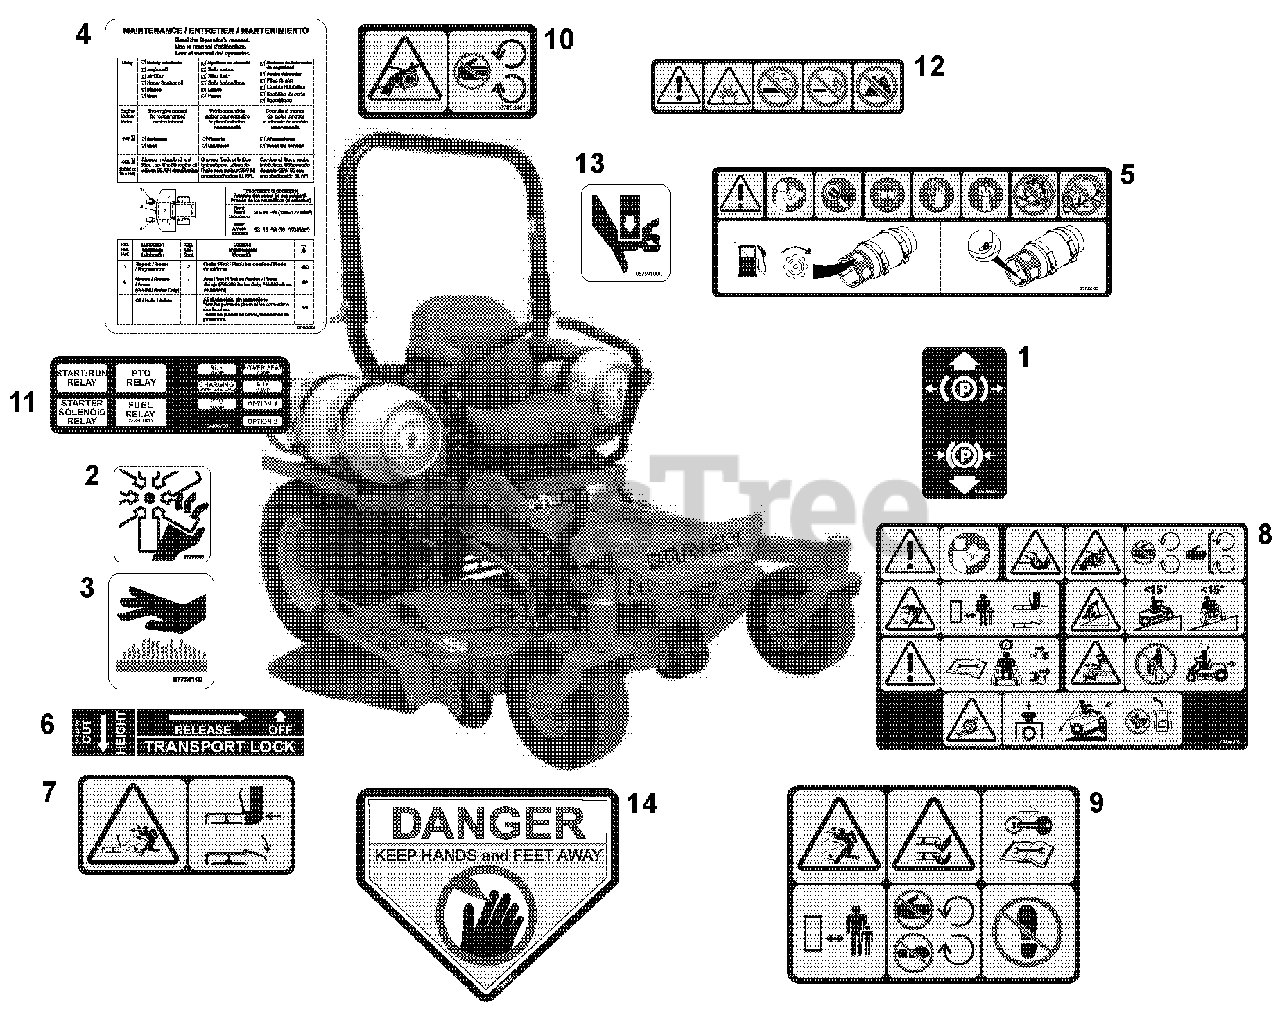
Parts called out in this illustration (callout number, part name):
1	Decal, Parking Brake Lever
2	Decal, Danger Fan
3	Decal, Hot Surface
4	Decal, Maintenance Instructions
5	Decal, Horz. Mower Tanks Only
6	Decal, Transport Lock
7	Decal, Deck Guarding Safety
8	Decal, Instruction
9	Decal, Mower Deck Safety
10	Decal, Safety Guarding
11	Decal, Fuse Box Layout
12	Decal, LP Safety
13	Decal, Pinch Point
14	Decal, Danger
